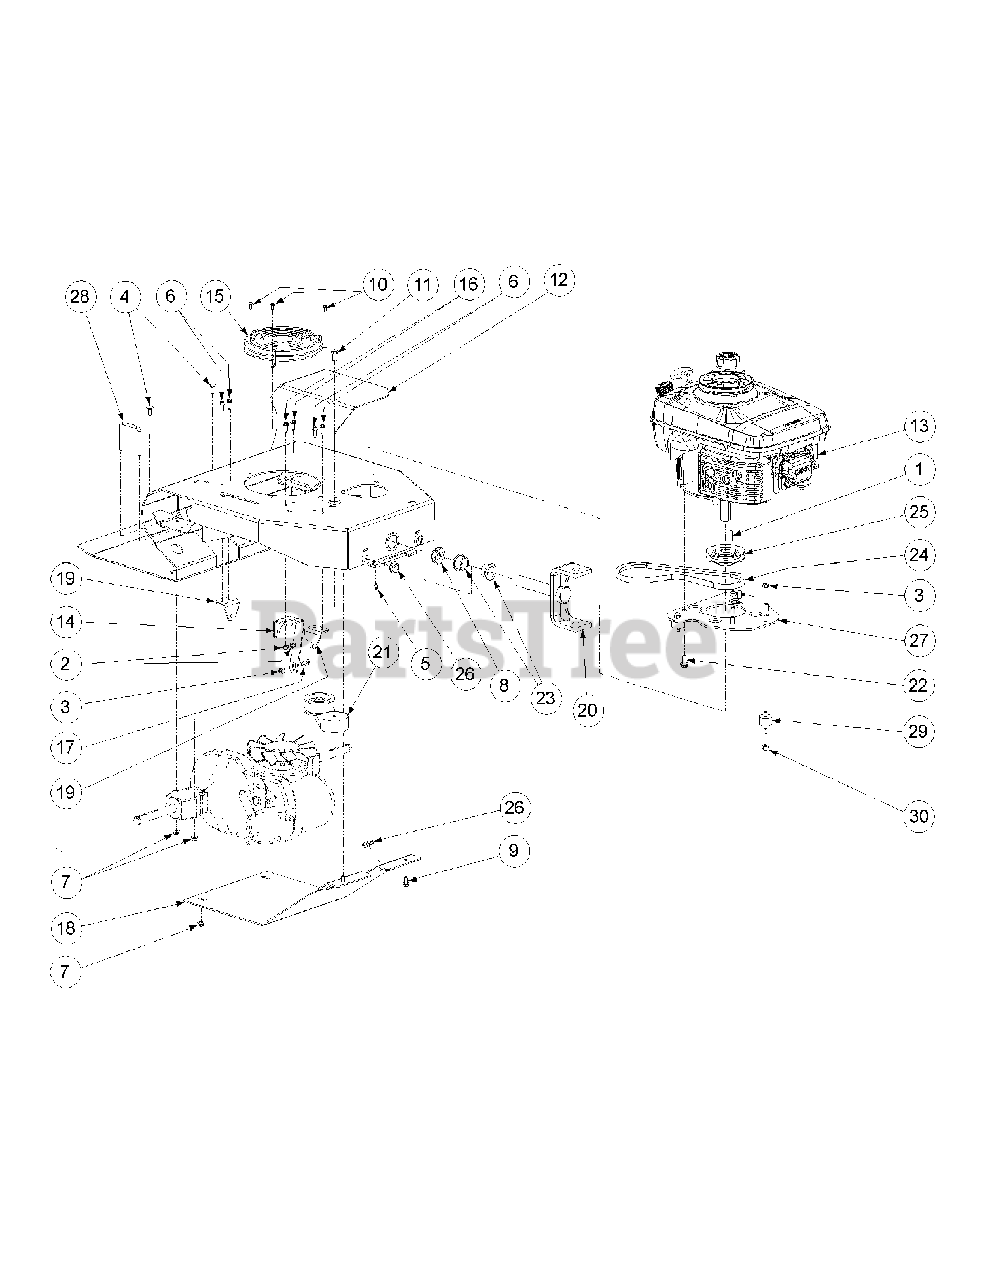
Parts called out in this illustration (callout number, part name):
1	Key, 3/16" x 1"
2	Nut, 1/4-20
3	Nut, 5/16-18
4	Carriage Bolt, 5/16-18 x .75
5	Grease Fitting, 1/4-28 x 3/16
6	Self Tapping Screw, 1/4-20 x .75
7	Nut, 5/16-18, Hex Flange Lock
8	Jam Nut, 1.0-14
9	Self Tapping Screw, 5/16-18 x .625
10	Self Tapping Screw, 10-24 x .50
11	Hex Cap Screw, 3/8-16 x .75
12	Fottstand Weldment
13	Engine, Kawasaki
15	Fan Guard
16	Hex Cap Screw, 1/4-20 x .75
17	Hex Cap Screw, 5/16-18 x .75
18	Transmission Skid Plate
19	Cable Mounting Bracket
20	Clevis Pin Pivot Weldment
21	Idler Arm
22	Self Tapping Screw, 3/8-16 x .875
23	Flange Bushing
24	V-Belt, A-Section
25	Cast Pulley
26	Rubber Grommet
29	Rubber Engine Mounting
30	Serrated Flange Nut, 5/16-18
